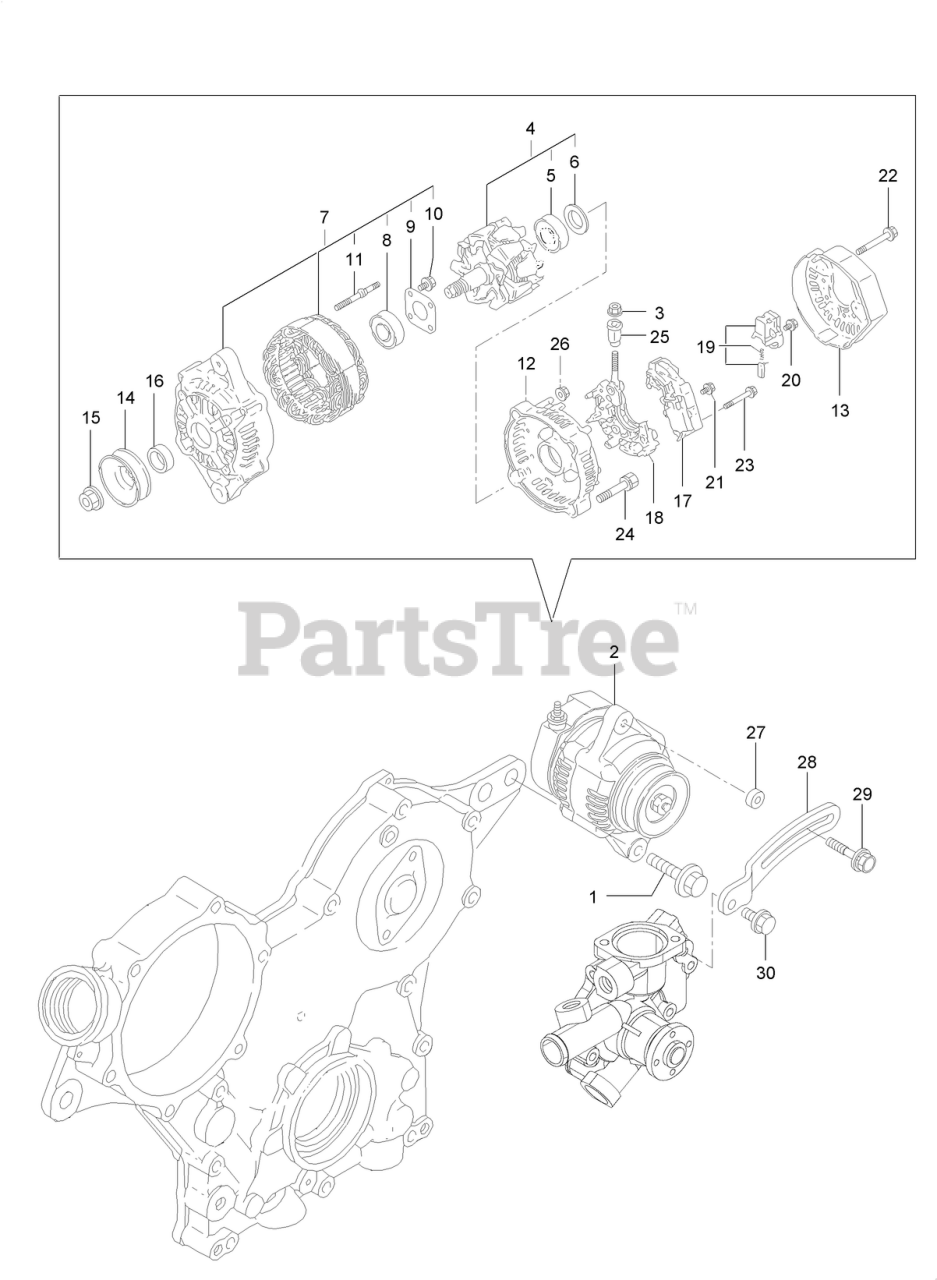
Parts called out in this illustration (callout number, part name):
2	ALTERNATOR
4	Rotor ASM
5	BEARING-BALL
7	FRAME ASM
8	BEARING-BALL
9	Plate-Retainer
17	REGULATOR ASM
25	Bushing-Insulation
28	ADJUSTER-BELT
